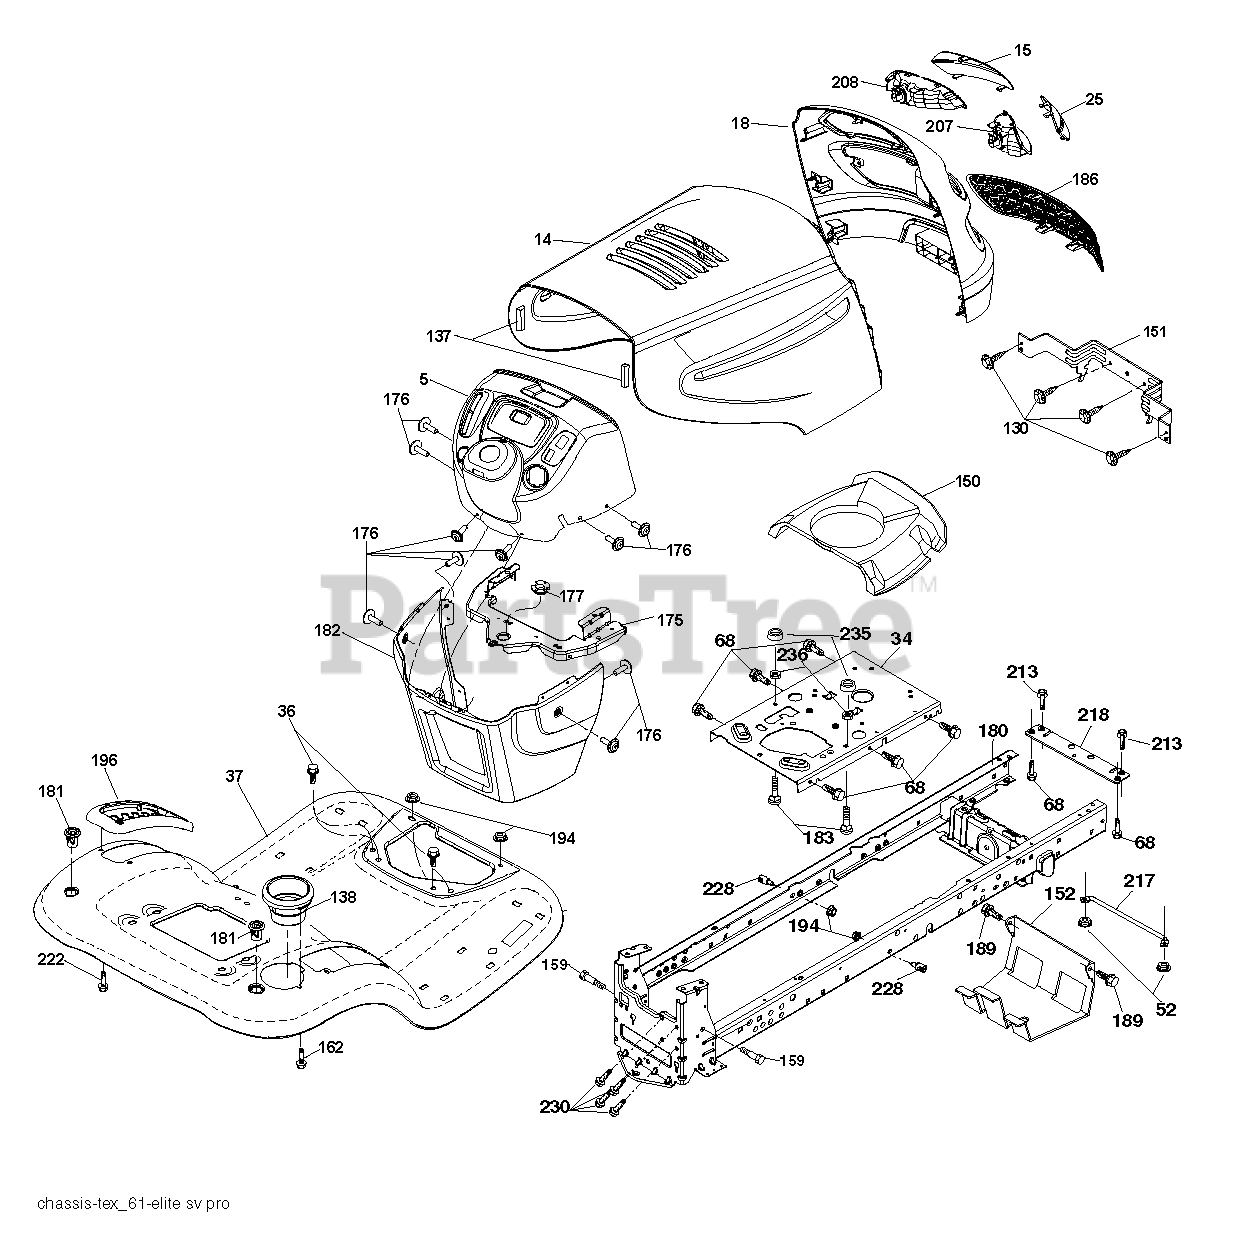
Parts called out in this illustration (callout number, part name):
5	DASH.P/L.TEX.CBL.CL.N/CHK.BLAC
34	PLATE.ENGINE.WELDED.CHASSIS
36	SCREW 5/16"
52	LOCKNUT
130	SCREW
137	BUMPER.HOOD.LARGE.1.75"
138	CUPHOLDER.TL.TEX.BLACK
151	BRACKET PIVOT
152	SHIELD BROWNING
159	SCREW, 3/8-16X3/4
162	SCREW.HI-LO.CONSOLE
175	CROSSMEMBER.LT
176	SCREW.#10-24X5/8.RN.QU
177	BUSHING STEERING
180	CHASSIS
181	FEND/FTRST.PCH.CPH.NFW
182	DASH.LOWER.LT.CCS
183	BOLT.5/16-18X1-1/4 FULL.THREAD
189	SCREW
194	NUT LOCK HEX FLANGE 5/16-18
196	CONSOLE.ASM.DECK.LIFT.TLT.BLAC
207	BEZEL GRILL RH
208	BEZEL GRILL LH
213	BOLT
217	ROD.PIVOT.HOOD
218	X-PIECE.HOOD.STOP.NON/
222	SCREW.1/4-20X5/8
228	STUD.FASTNER.W/ANTI-ROTATE
230	SHOULDER BOLT 5/16-18TT
235	SPACER FENDER
236	NUT.CENTERLOCK.5/16-
